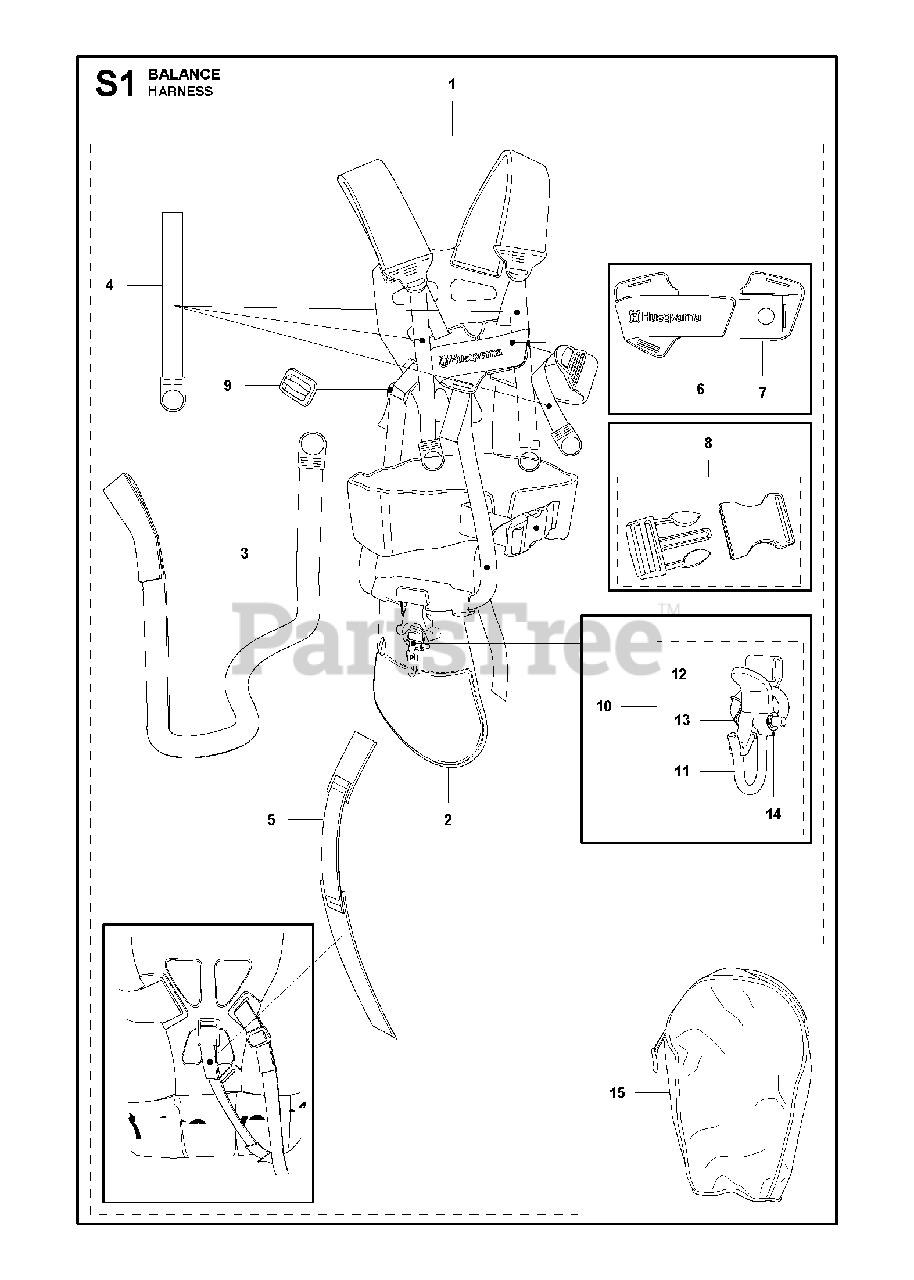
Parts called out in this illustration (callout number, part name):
1	HARNESS BALANCE X
1	HUS BALANCE X TRIO HA
2	HIP BAND
3	BAND
4	BAND
5	BAND
6	FRONT PIECE
7	FRONT PIECE
8	BUCKLE
9	BUCKLE
10	WELT HOOK
11	HOOK
12	CATCH *
13	SPRING LOCKING
14	E-RING 5
15	TOOL BAG
